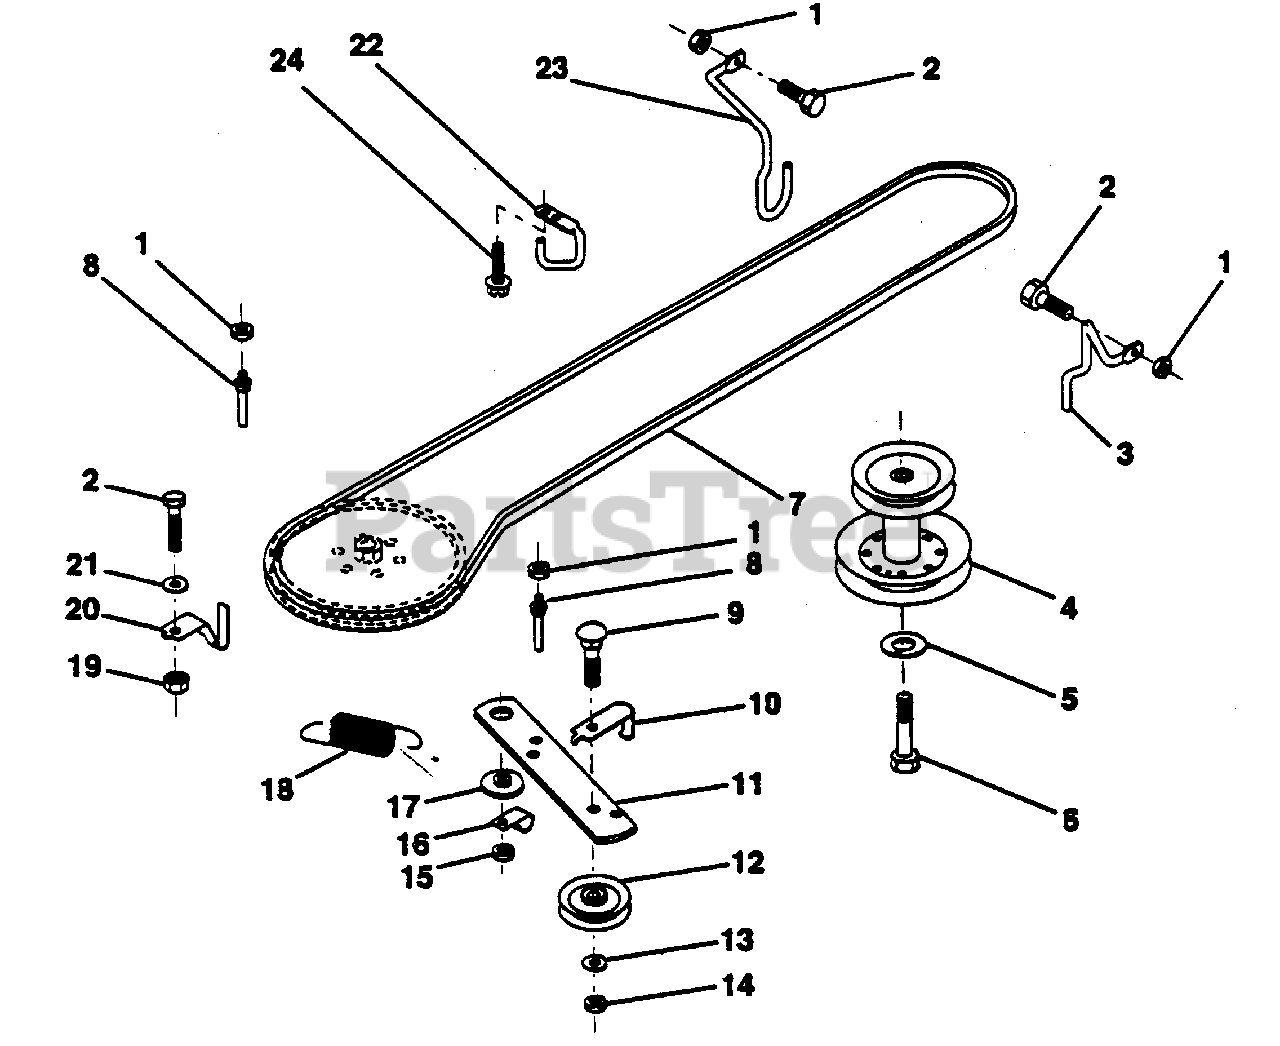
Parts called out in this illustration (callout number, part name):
1	Nut, Crownlock 5/16-18
2	Bolt, Hex Hd 5/16-18 UNC x 3/4
3	Keeper,Mower Drive, R. H.
4	Pulley, Engine
5	Washer, Lock 7/16
6	Bolt Hex 7/16-20 Gr. 5
7	Traction, V-Belt Drive
8	Keeper, T/A Ground Drive Belt
9	Bolt, Carr.?? 3/8-16 UNC x 1-1/2
10	Keeper, Belt Ground Drive Idler
11	Arm, Ground Drive Clutch
13	Washer 13/32 x 13/16 x 16 Ga.
14	Nut, Centerlock 3/8-16 UNC
15	Nut, Crownlock 3/8-16 UNC
16	Clip, Insulated
17	Spacer, Retainer
18	Spring Extension
19	Nut, Keps 5/16-18 UNC
20	Keeper, T/A Ground Drive Belt
21	Washer 11/32 x 5/8 x 16 Ga.
22	Keeper, Frame Ground Drive Belt
23	Keeper, Mower Drive, L. H.
24	Screw, Thd. Cut 1/4 x 20 x 1/2
